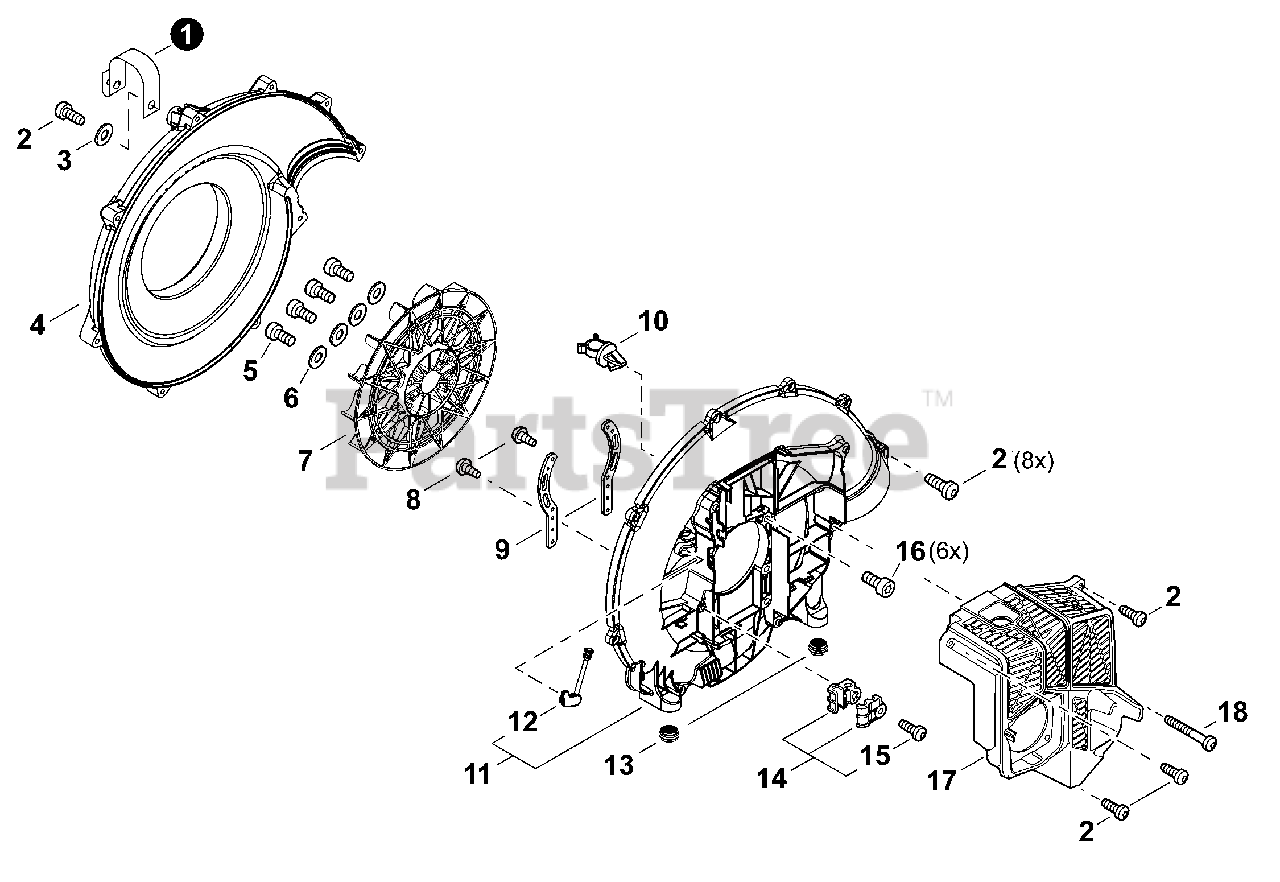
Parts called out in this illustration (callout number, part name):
1	STRAP, SAFETY 1.2×100
2	BOLT, TORX 5×20
3	WASHER 5.5×16×2T
4	COVER, FAN
5	BOLT, TORX 5×30
6	WASHER 5.5×16×2T
7	FAN, BLOWER
8	SCREW TAPPING 3×12
9	BRACKET, ENGINE
10	CLIP, CABLE
11	FAN CASE SET
12	GROMMET
13	CUSHION
14	CABLE HOLDER SET
15	BOLT, TORX 5×25
16	BOLT, TORX 5×30
17	COVER, ENGINE
18	BOLT, TORX 5×55
